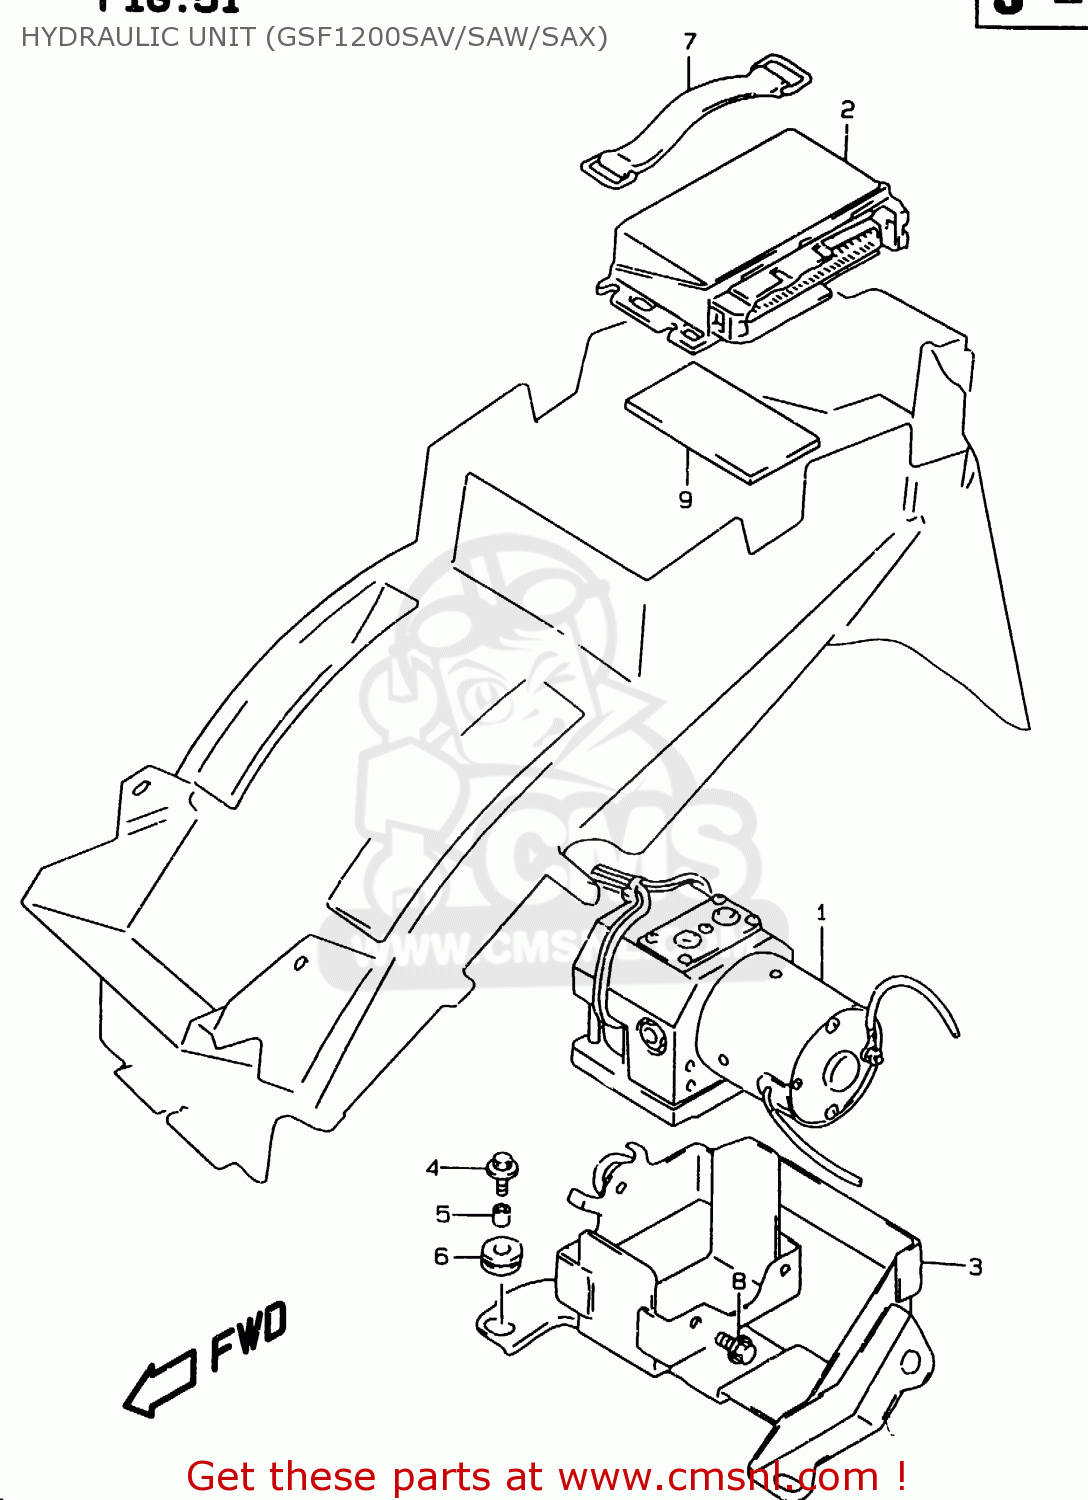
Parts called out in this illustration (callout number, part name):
1	UNIT ASSY,HYDRAULIC ABS
2	ECU ASSY,ABS
3	HOLDER,HYDRAULIC UNIT
4	BOLT 6X20,WITH PLAIN WASHER
5	SPACER(6.5X9X7)
6	CUSHION
7	BAND
8	BOLT
9	PROTECTOR,BATTERY(70X100X6)
